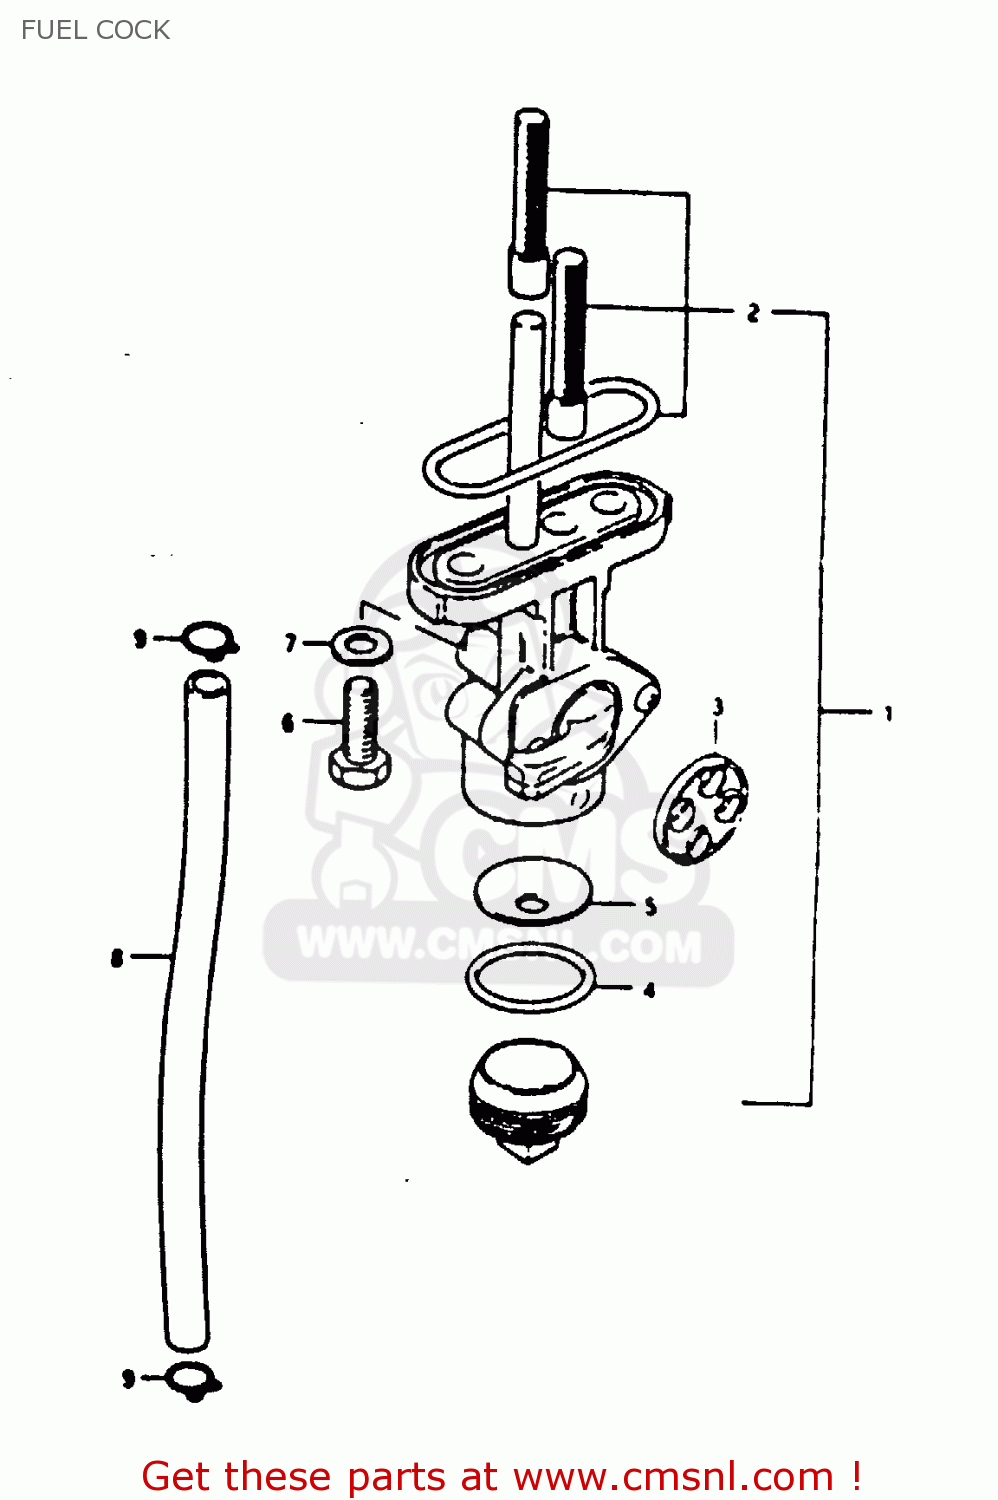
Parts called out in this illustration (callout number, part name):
1	COCK ASSEMBLY,FUEL
2	GASKET,FILTER (NAS)
3	NET,STRAINER
4	FILTER SET,FUEL COCK
5	GASKET,LEVER (NAS)
6	BOLT L:16
7	GASKET
8	HOSE
9	CLIP
